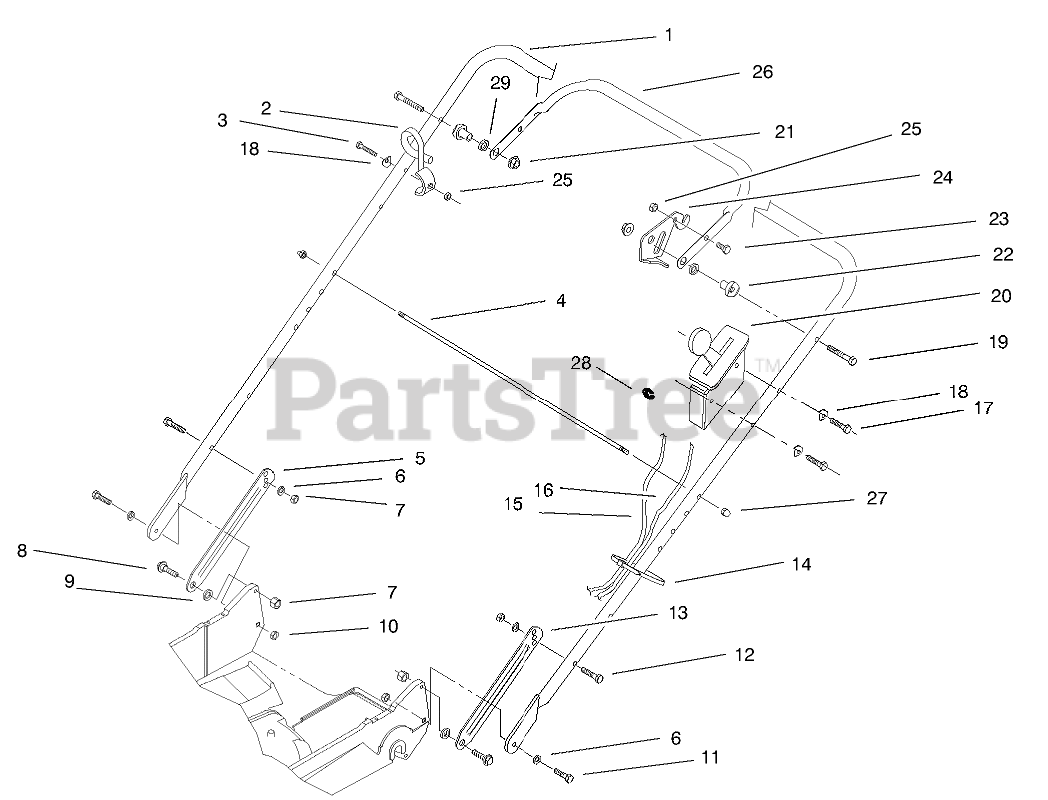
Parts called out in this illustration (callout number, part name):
2	GUIDE-ROPE
3	SCREW-HH
4	ROD-SUPPORT, BAG
5	LATCH-HANDLE, RH
6	WASHER-BELLEVILLE
7	NUT-LOCK, NI
8	SCREW-SHOULDER
9	SPACER
10	NUT-LOCK, NI
11	SCREW-HH
12	SCREW-HH
13	LATCH-HANDLE, LH
14	TIE-CABLE
15	CABLE - BRAKE
16	CABLE - THROTTLE
17	SCREW-HH
18	WASHER
19	SCREW-HH
20	BRACKET-THROTTLE CONTROL HEAD
21	NUT-LOCK, NI
22	SPACER-SUPPORT
23	SCREW-HH
24	LEVER-CONTROL
25	NUT-LOCK, NI
26	BAR-CONTROL
27	NUT-CAP
28	E-RING
29	SPACER-NYLON
